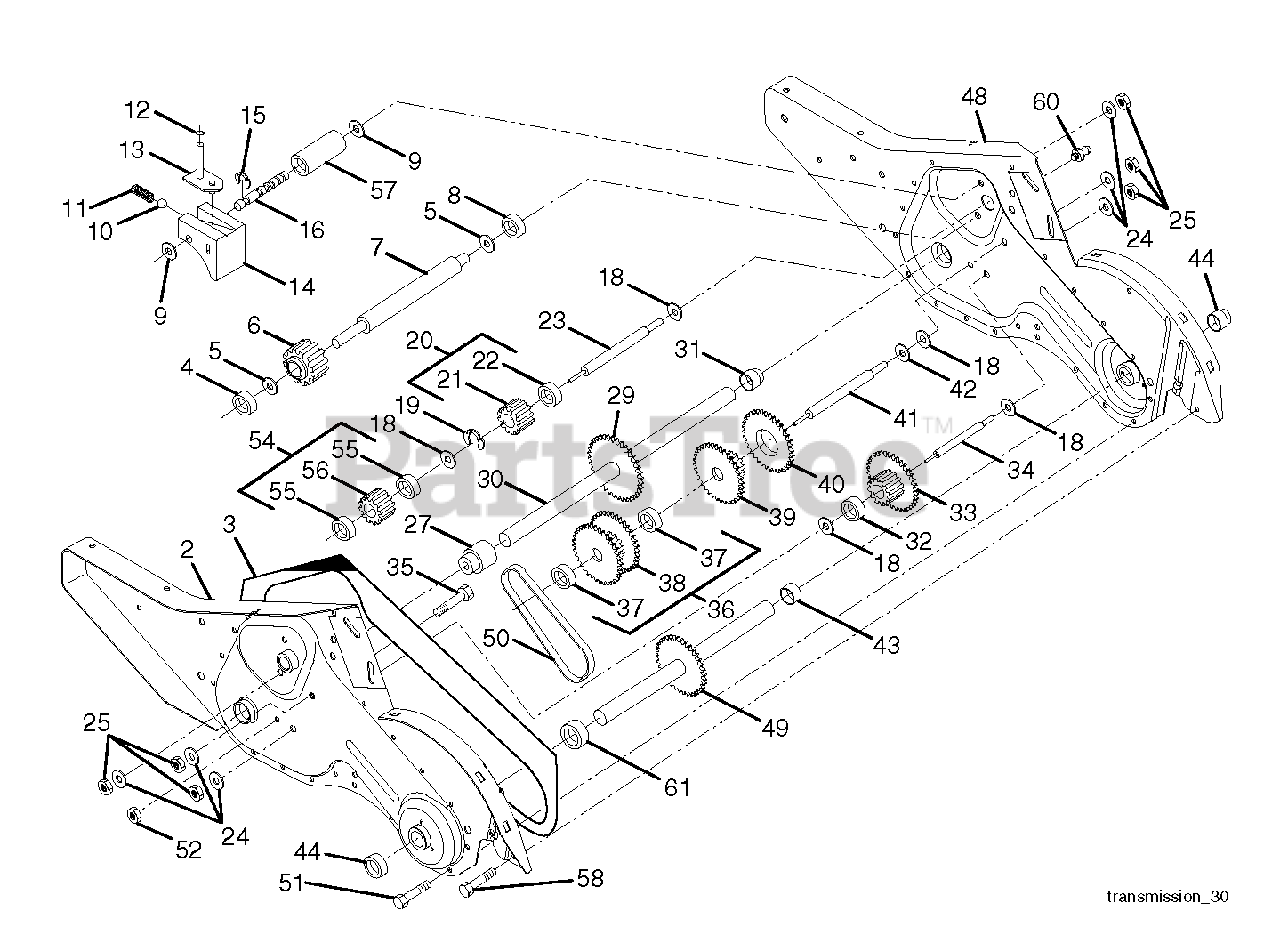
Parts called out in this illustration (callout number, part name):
2	GEARCASE.ASM.DRT.LH.
3	GASKET.GEARCASE.CRT/DRT.
4	NEEDLE BRNG LT
5	THRUST WASHER
6	PINION INPUT DRT TILLER
7	SHAFT.INPUT.D.9TEETH
9	WASHER, SEAL (2 2)
10	BALL, STEEL
11	SPRING-SHIFT CRT
13	BRACKET ASM.SHIFT.CRT
14	SHIFT FORK TI
16	SHAFT.SHIFT.DRT
20	GEAR ASSY CRT
21	GEAR-REV IDLR CRT
22	NEEDLE BEARING TI
23	SHAFT.IDLER.REVERSE.CRT
24	LOCKWASHER
25	NUT.ASF.HEX.7/16
27	BEARING.GROUND.DRIVE
30	GROUND SHAFT ASS'Y
31	BEARING, SHAFT RH CRT
33	SPRCKT 8 GEAR CRT
34	SHAFT.SECONDARY.REDUCTION.CRT
35	SCRW WHIZ LOK CRT
36	GEAR & SPROCKET.ASM.WBEARIN
37	NEEDLE BEARING
38	ASM.GEAR & SPROCKET
39	GEAR.CLUSTER.DRT.TILLER
41	SHAFT.REDUCTION.FIRST.DRT
42	BRNG RACE T
44	SEAL ASM, OIL
48	GEARCASE.ASM.DRT.RH.
49	SHAFT.ASM.TINE
50	CHAIN.TILLER
54	GEAR.ASM.DRT.TILLER
55	DRAWN CUP ROLLER BEARING W/CAG
56	GEAR.DRT.IDLER
57	SPACER.SPLIT
58	BOLT SHOULDER 1/4-20 UNC X.875
60	FITTING.GREASE.TAPERED
61	SPACER.1.015X1.50X.650
